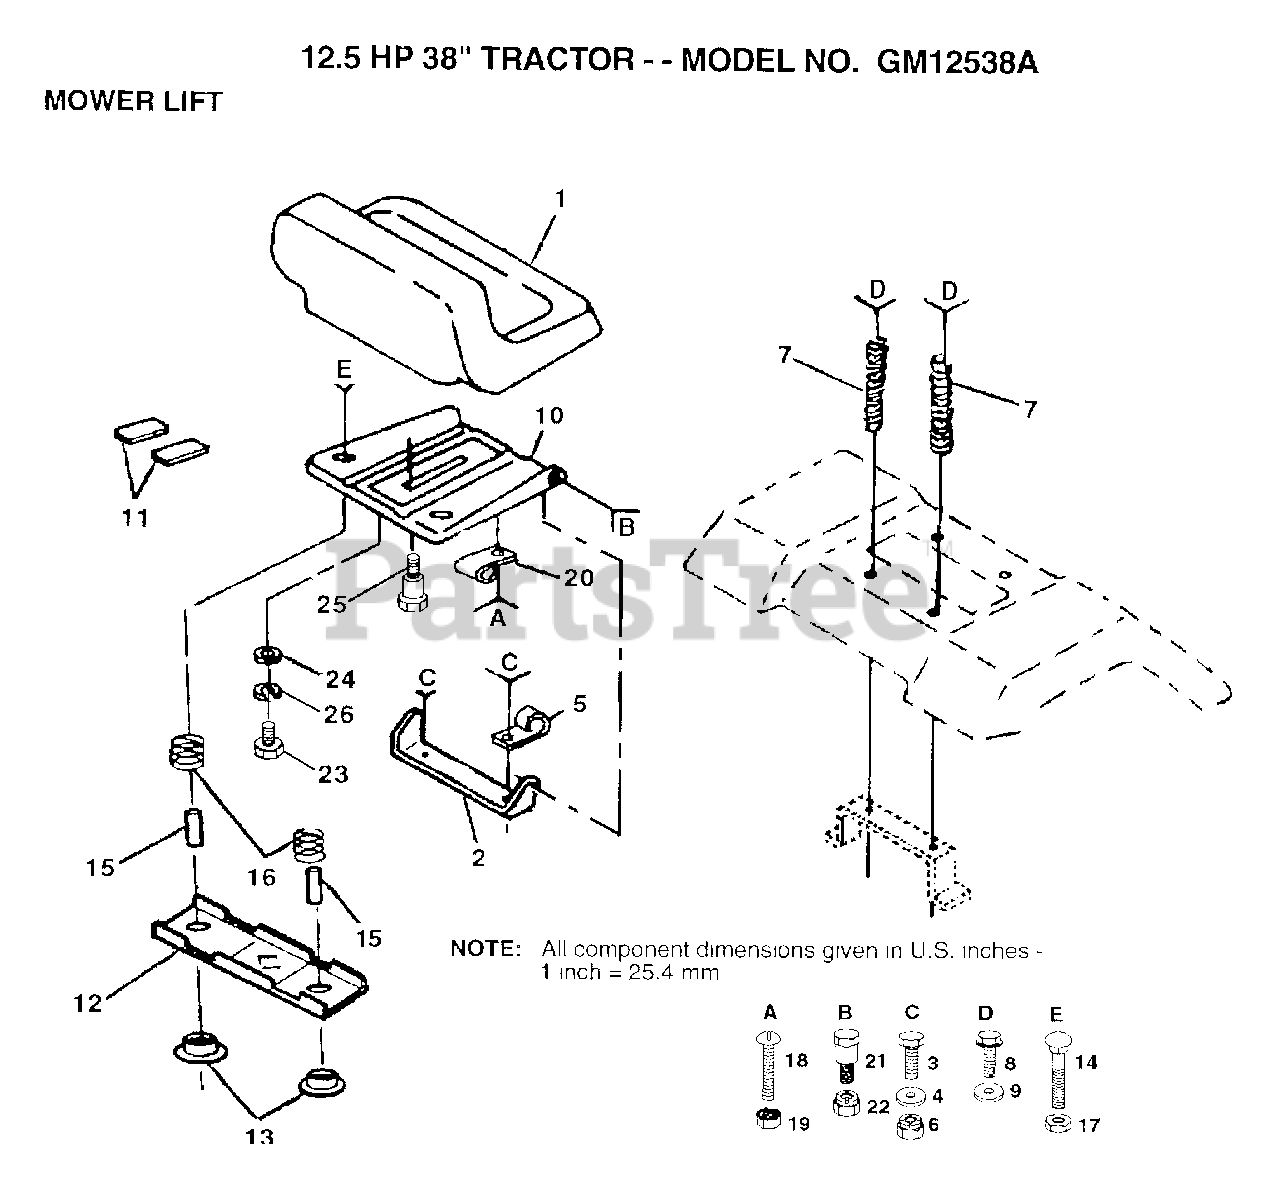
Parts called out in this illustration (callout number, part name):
4	WASHER PM
5	CLIP T
7	SPRING COMPRESSIO
8	SCREW GTV
9	WASHER
11	STRIP FORM
12	BRKT SWITCH
13	BUSHING
15	SPLIT SPACER
16	SPRING
19	"NUT,KEPS"
23	BOLT
24	WASHER
25	"BOLT,SHOULDER"
26	LOCKWASHER
